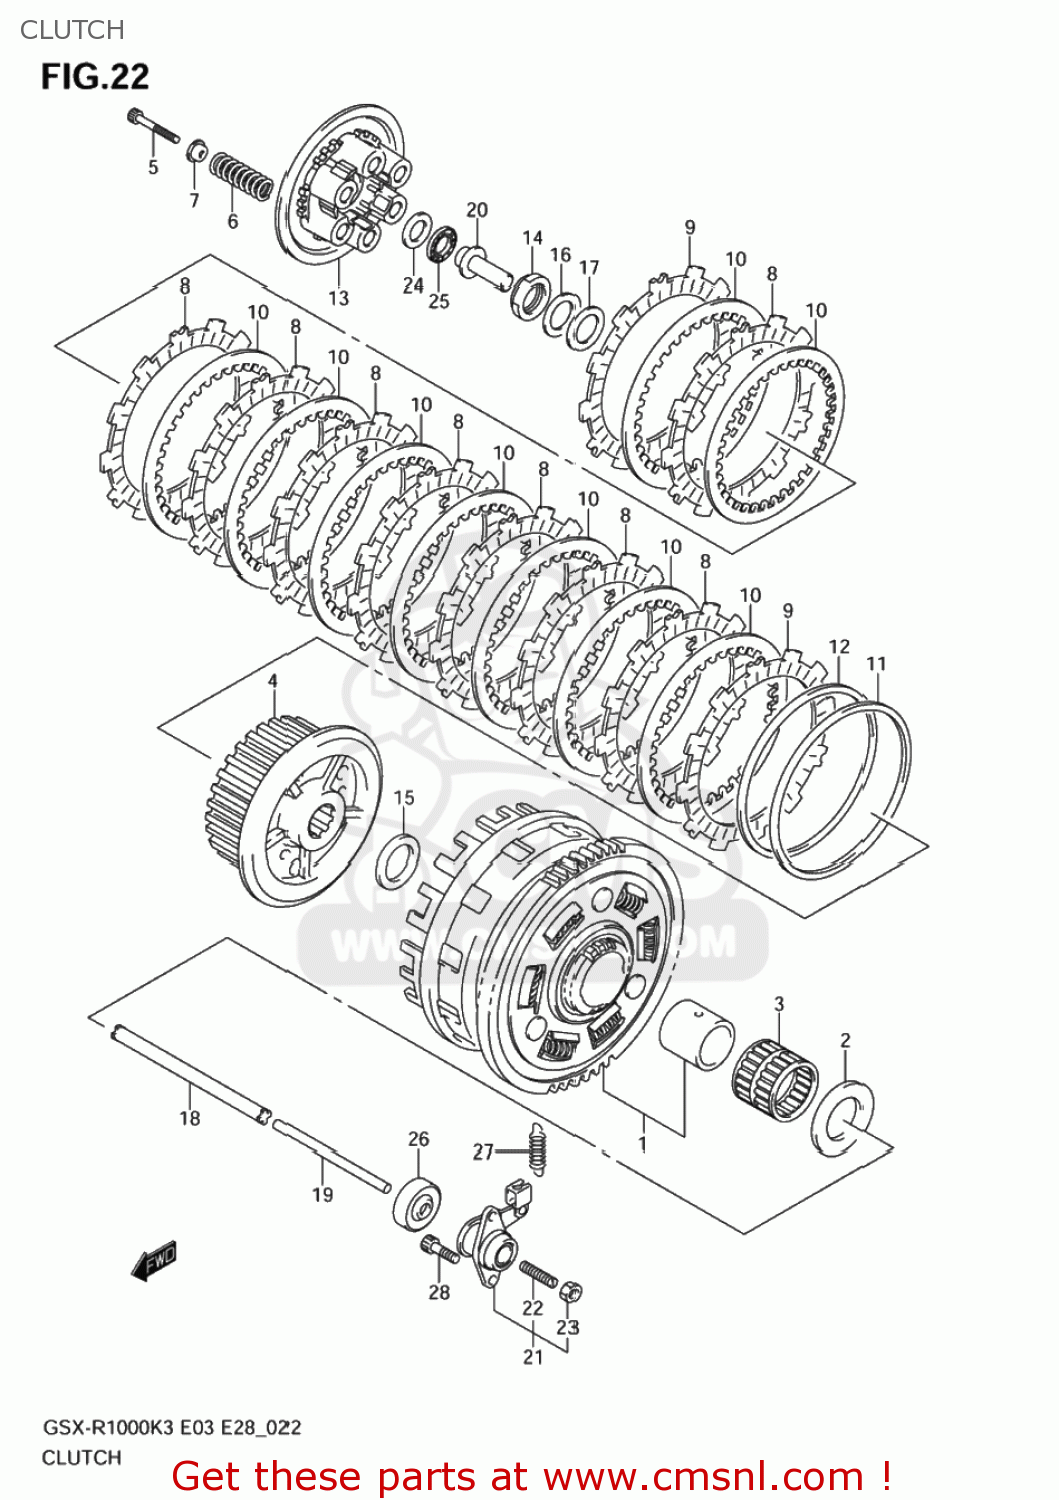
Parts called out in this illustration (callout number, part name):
1	GEAR ASSY,PRI DRIVEN
2	WASHER(25X54X2.4)
3	BEARING(35X40X35.8)
4	HUB,CLUTCH SLEEVE
5	BOLT,CLUTCH SPRING
6	SPRING,CLUTCH
7	WASHER
8	PLATE,CLUTCH DRIVE NO.1 (NAS)
9	PLATE,CLUTCH DRIVE NO.2 (NAS)
10	PLATE,CLUTCH DRIVEN (NAS)
11	SEAT,CLUTCH PLATE WAVE WASHER
12	WASHER,CLUTCH PLATE WAVE
13	DISC,CLUTCH PRESSURE
14	NUT
15	WASHER(25X50X2.5)
16	WASHER
17	SHIM(25X38X1)
18	ROD,CLUTCH PUSH,R
19	ROD,CLUTCH PUSH,L
20	PIECE,CLUTCH PUSH
21	SCREW ASSY,CLUTCH RELEASE
22	SCREW(6X25)
23	NUT
24	WASHER(15.5X28X1)
25	BEARING(15X28X2)
26	SEAL,OIL(6X34X10)
27	SPRING
28	BOLT
